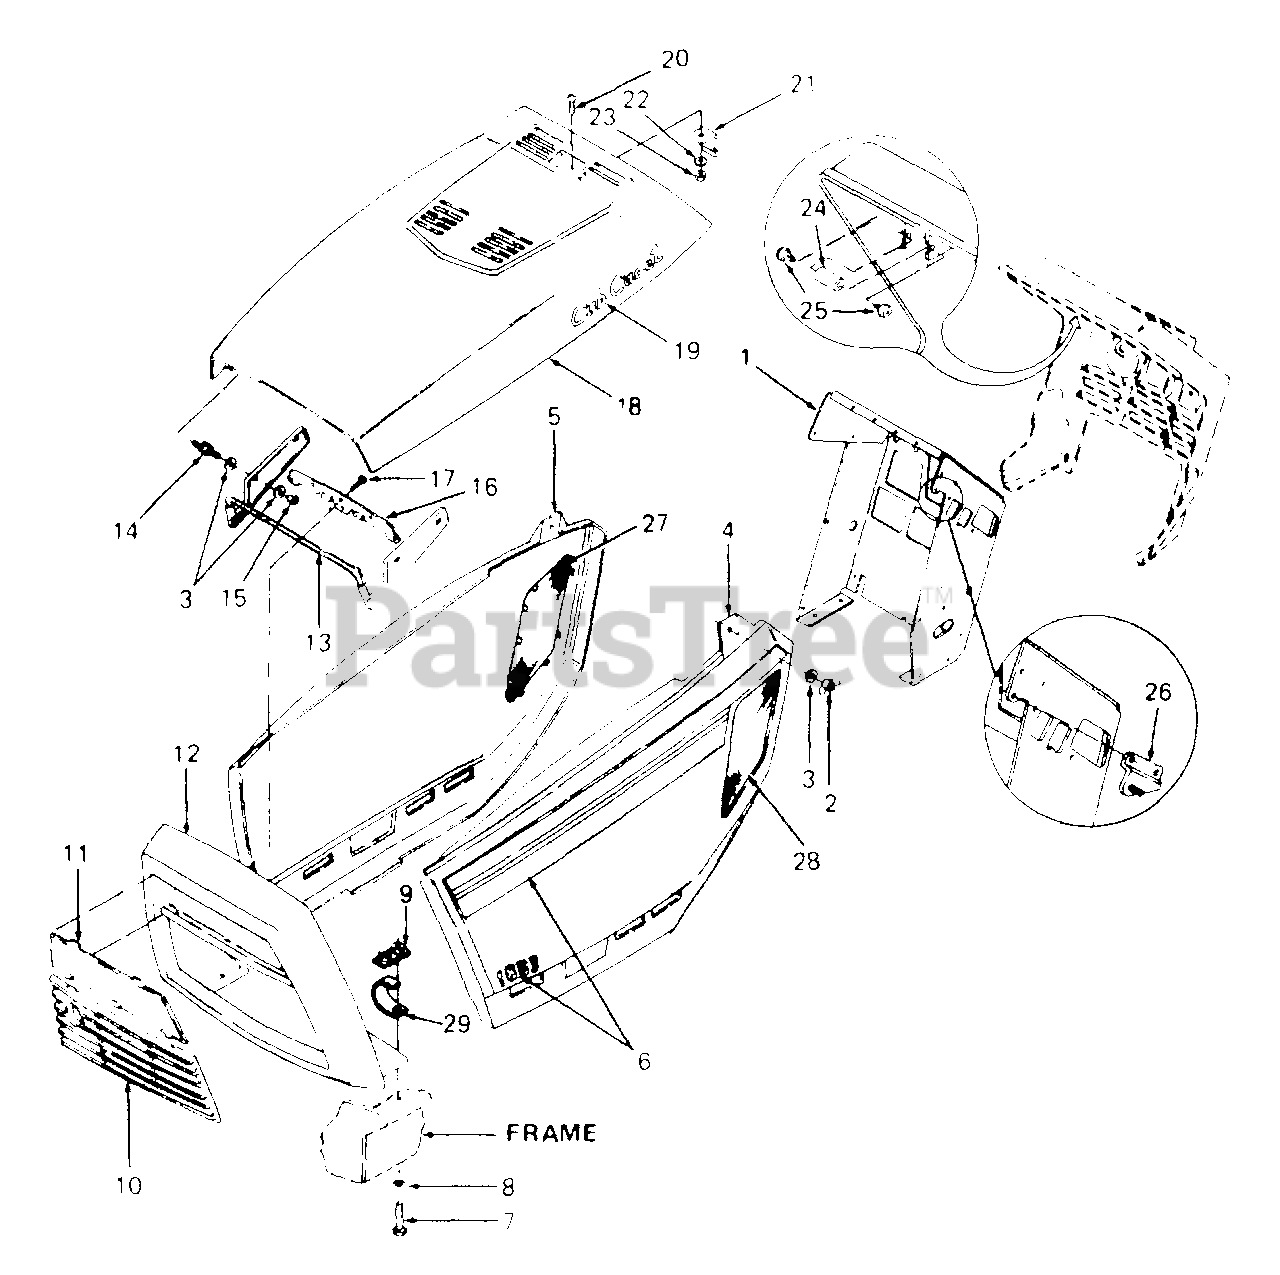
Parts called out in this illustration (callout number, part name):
3	Washer, Flat, .251 X .62 X .052 Thk 10
4	Panel, LH Side
5	Panel, RH Side
6	Graphics Kit, LH Side Panel
7	Screw, Hex Cap, 5/16-18 X 1.0 Lg GR5
8	Washer, Lock, 5/16
9	Retainer, Grille Housing
10	Grille, Insert
11	Grille, Lens
12	Grille Hsg
15	Nut, Hex Patch Lock, 1/4-20
18	Hood
19	Graphic, Cub Cadet Script w/Studs
20	Screw, Truss Hd, #8-32 X .38 Lg
21	Clip, Hood Latch
22	Washer, Flat, .16 X .38 X .045 Thk
23	Nut, Hex Keps, 08-32
24	Pin, Latch
25	Screw, Phillips Hd Truss Mach, 1/4-20 X .50 Lg
